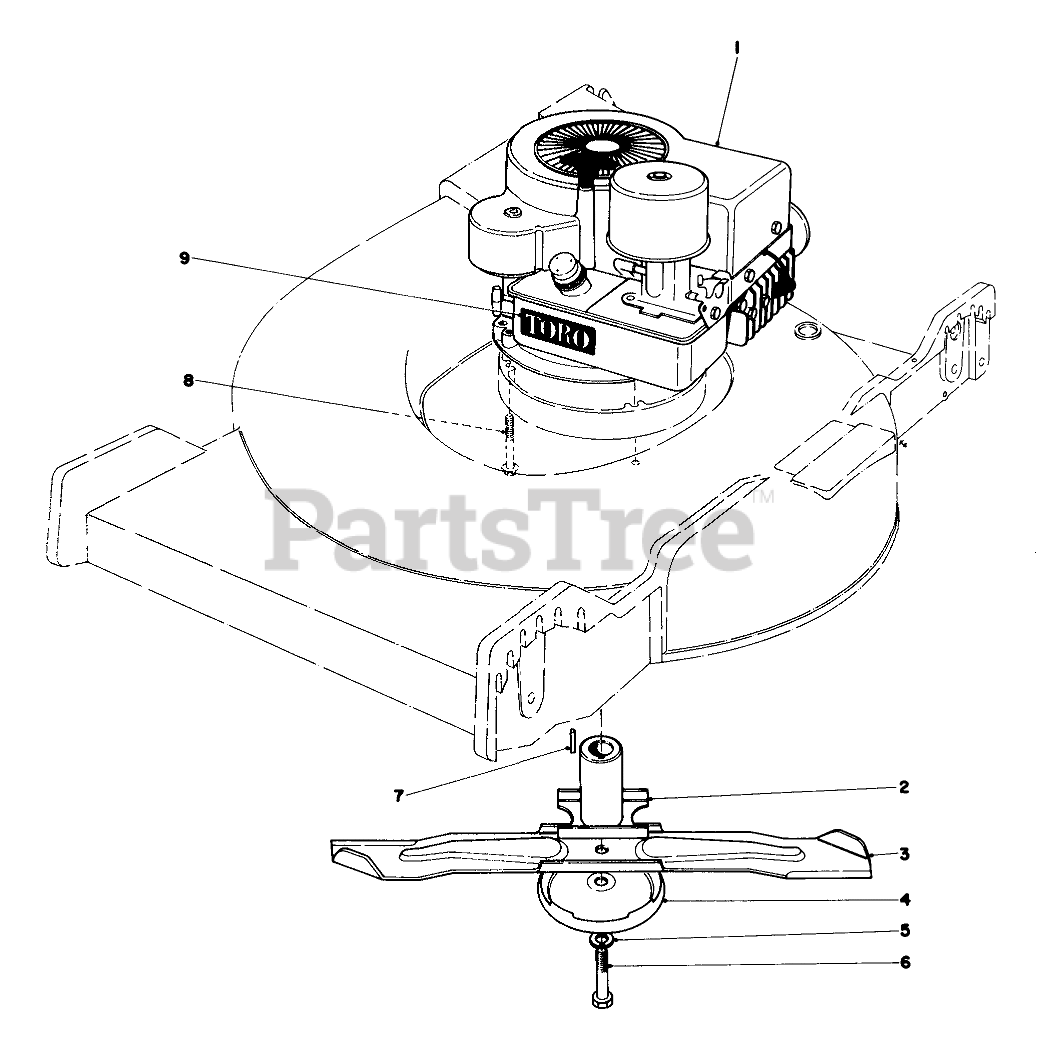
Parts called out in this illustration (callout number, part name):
1	Engine
2	Blade Retainer
3	Blade
4	AntiScalp Cup
5	WASHER-LOCK
6	SCREW-BLADE
7	KEY-SQUARE
8	3/8-16 X 2-3/4 CAPSCR
9	Decal Toro
